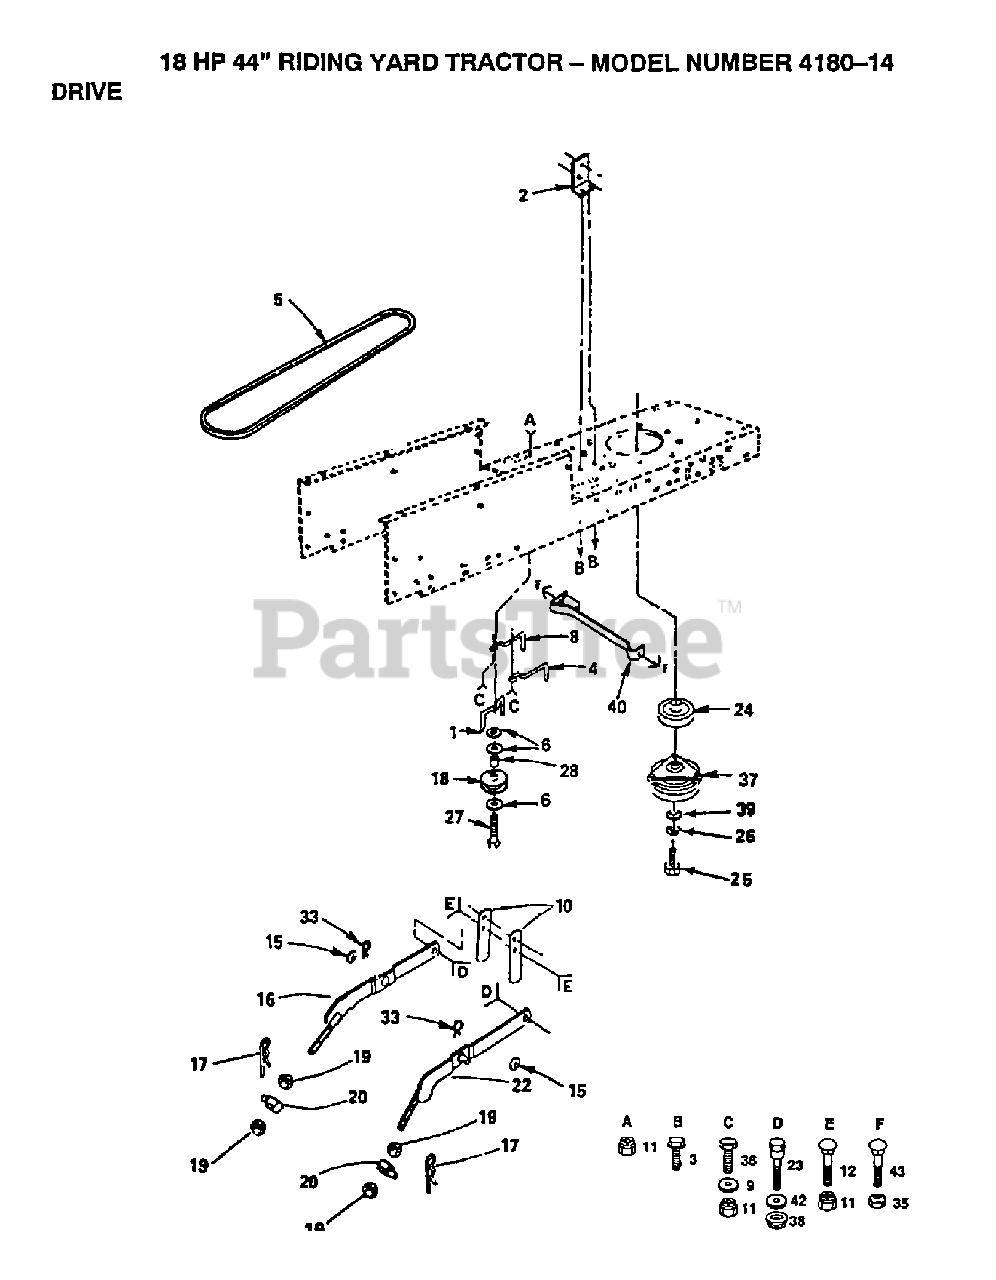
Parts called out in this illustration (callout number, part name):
1	BELT KEEPER LT
2	BRACKET LT
4	KEEPER,BLT ENG LT
5	BELT.GROUND.DRIVE
9	WASHER
11	LOCKNUT
15	WASHER T
16	LH SUSP ARM ASM
17	SPRING H
18	FLAT IDLER PULLEY
22	RH SUSP ARM ASM
23	BOLT, SHOULDER LT
24	ENGINE PULLEY
26	LOCKWASHER
28	SPACER T
33	SPRING.RETAINER
35	LOCKNUT
36	BOLT
40	KIT RETAINER YTH
42	WASHER T
43	BOLT
